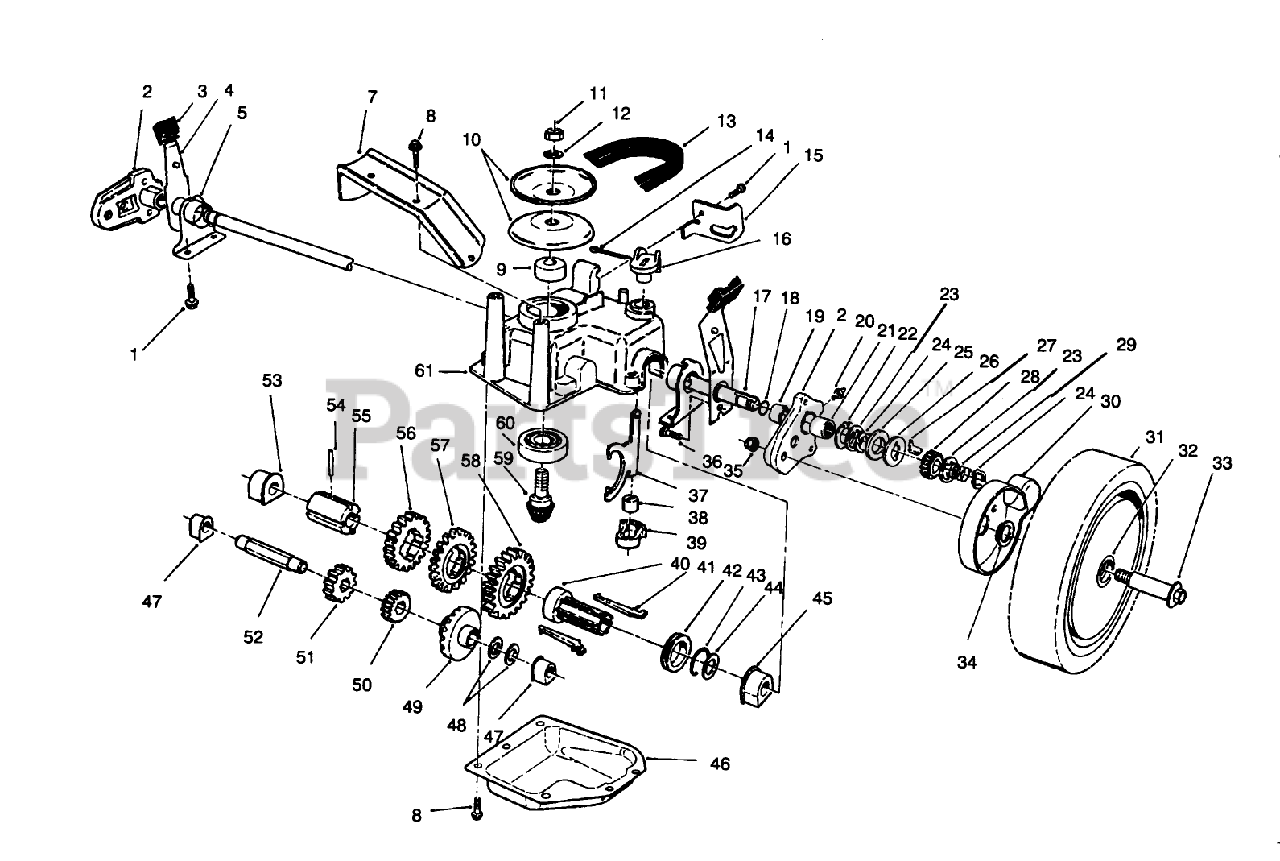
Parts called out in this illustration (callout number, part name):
1	SCREW-HWHTF
2	PIVOT ARM ASM
3	KNOB-ARM
4	SPRING ARM ASM
5	CAP-END
8	SCREW-HWHTF
9	SPACER
11	NUT-HEX
12	WASHER-FLAT
13	V-BELT
14	PIN-COTTER
15	RETAINER-CABLE
16	LEVER-SHIFT
17	SHAFT-OUTPUT
18	O-RING
19	BUSHING
20	FITTING-GREASE
22	WASHER-ARM, PIVOT
23	WASHER-THRUST, KEYED
24	RING-RETAINING,CLIP
25	RING-FRICTION
26	WASHER-CLUTCH
27	KEY-ROCKING, LH
28	GEAR-PINION
29	SPRING-COMPRESSION
30	COVER-WHEEL
31	WHL & TIRE ASSEMBLY
32	BUSHING
33	WHEEL BOLT
34	SPACER-COVER, WHEEL
35	NUT-LOCK
36	SCREW-HSH, THREAD FORMING
37	YOKE-SHIFT
38	BUSHING-YOKE
39	RETAINER-FORK, SHIFT
40	SLEEVE-KEY, SHIFT
41	KEY-SHIFT
42	COLLAR-SHIFT
43	CLIP-SPRING
44	WASHER-PLAIN
45	BUSHING-OUTPUT
47	BUSHING
48	WASHER-THRUST
50	PINION-20T
51	PINION-25T
53	BUSHING
54	PIN-ROLL
55	SLEEVE-GEAR
56	GEAR-39T
57	GEAR-44T
58	GEAR-49T
60	BEARING-BALL
61	CASE-GEAR, UPPER
